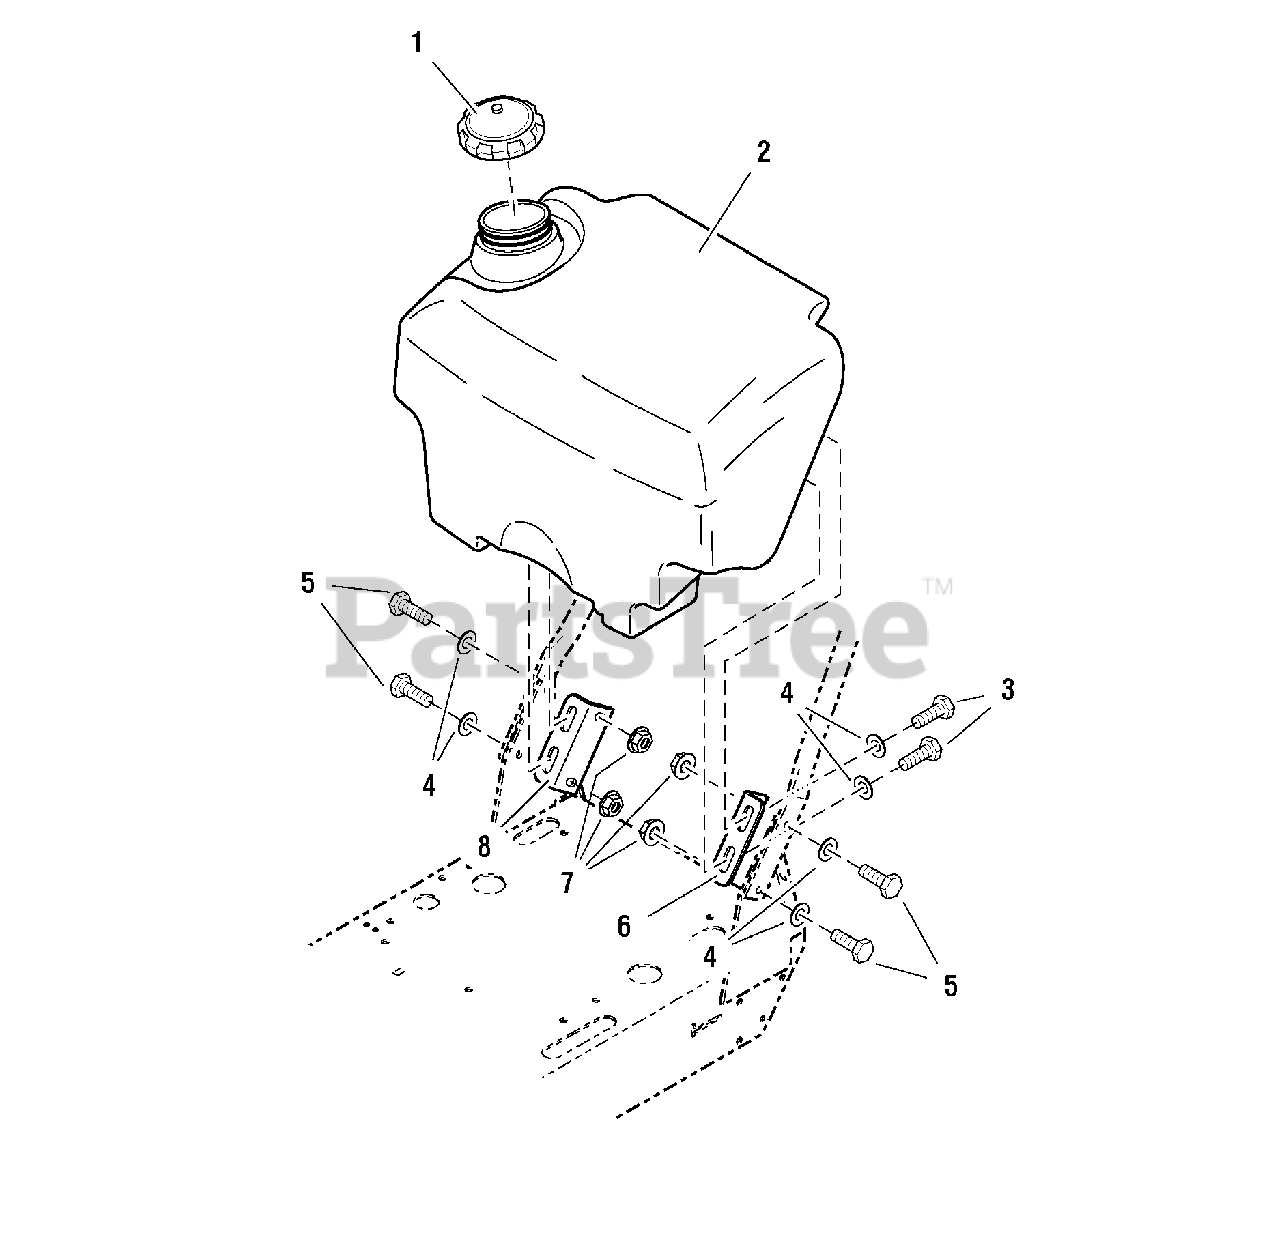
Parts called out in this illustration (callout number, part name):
1	FUEL TANK CAP
3	CAPSCREW, Hex Head, 3/8-16 x 3/4
4	WASHER, 3/8
5	CAPSCREW, Hex Head, 3/8-16 x 1-1/4
6	FUEL TANK MOUNT - LH
7	NUT, Hex Serrated Flange, 3/8-16
8	FUEL TANK MOUNT - RH
